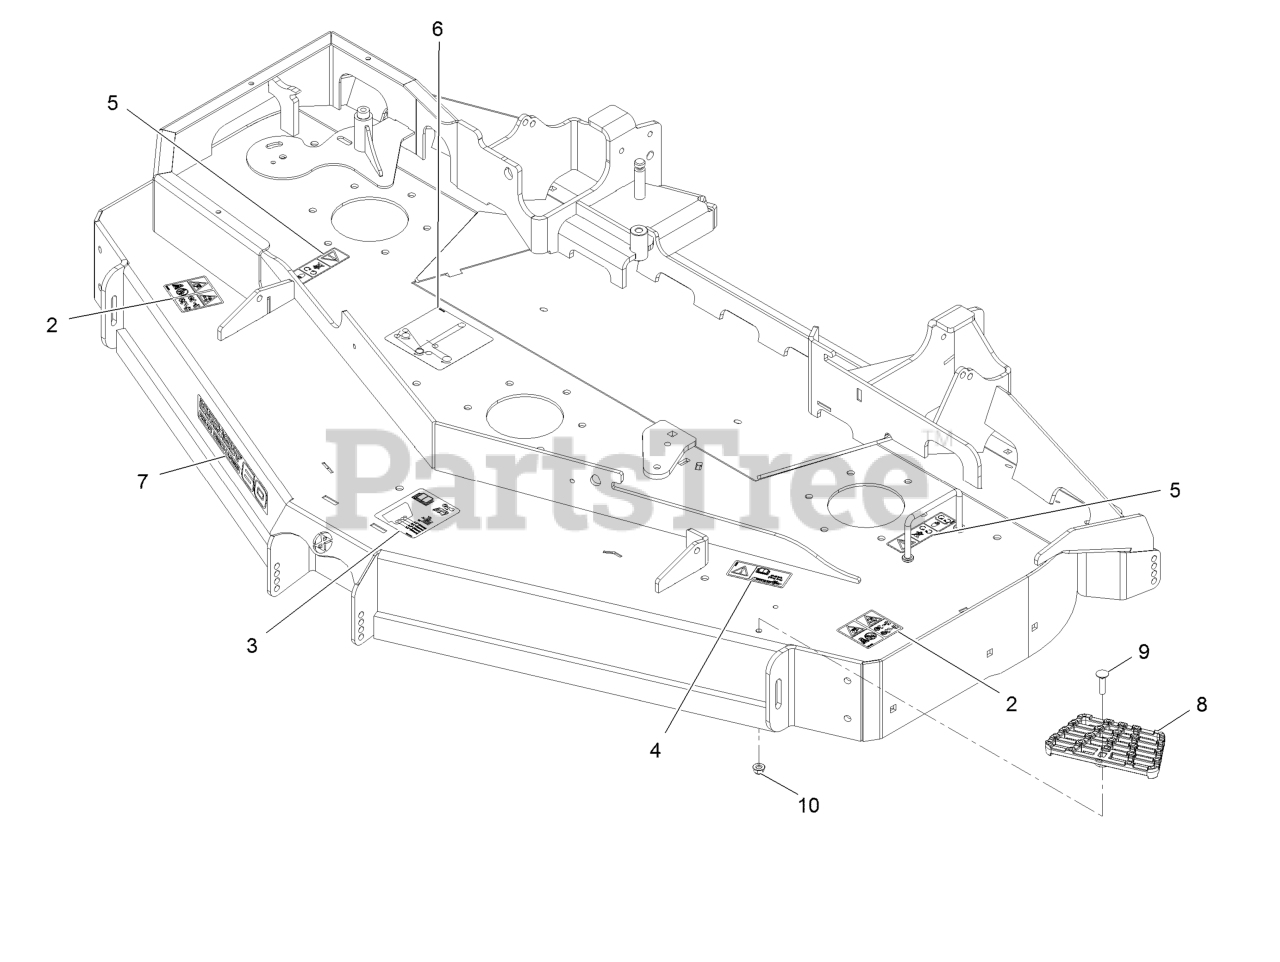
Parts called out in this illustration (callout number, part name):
2	Decal-Danger Thrown Obj
3	Decal-Roller, Anti-Scalp
4	Decal-Bolt Torque
5	Decal-Missing, Cover
6	Decal-Routing, Belt
7	Decal, 60Rd
8	Step-Deck
9	Screw-CARR
10	Nut-HF, NI
